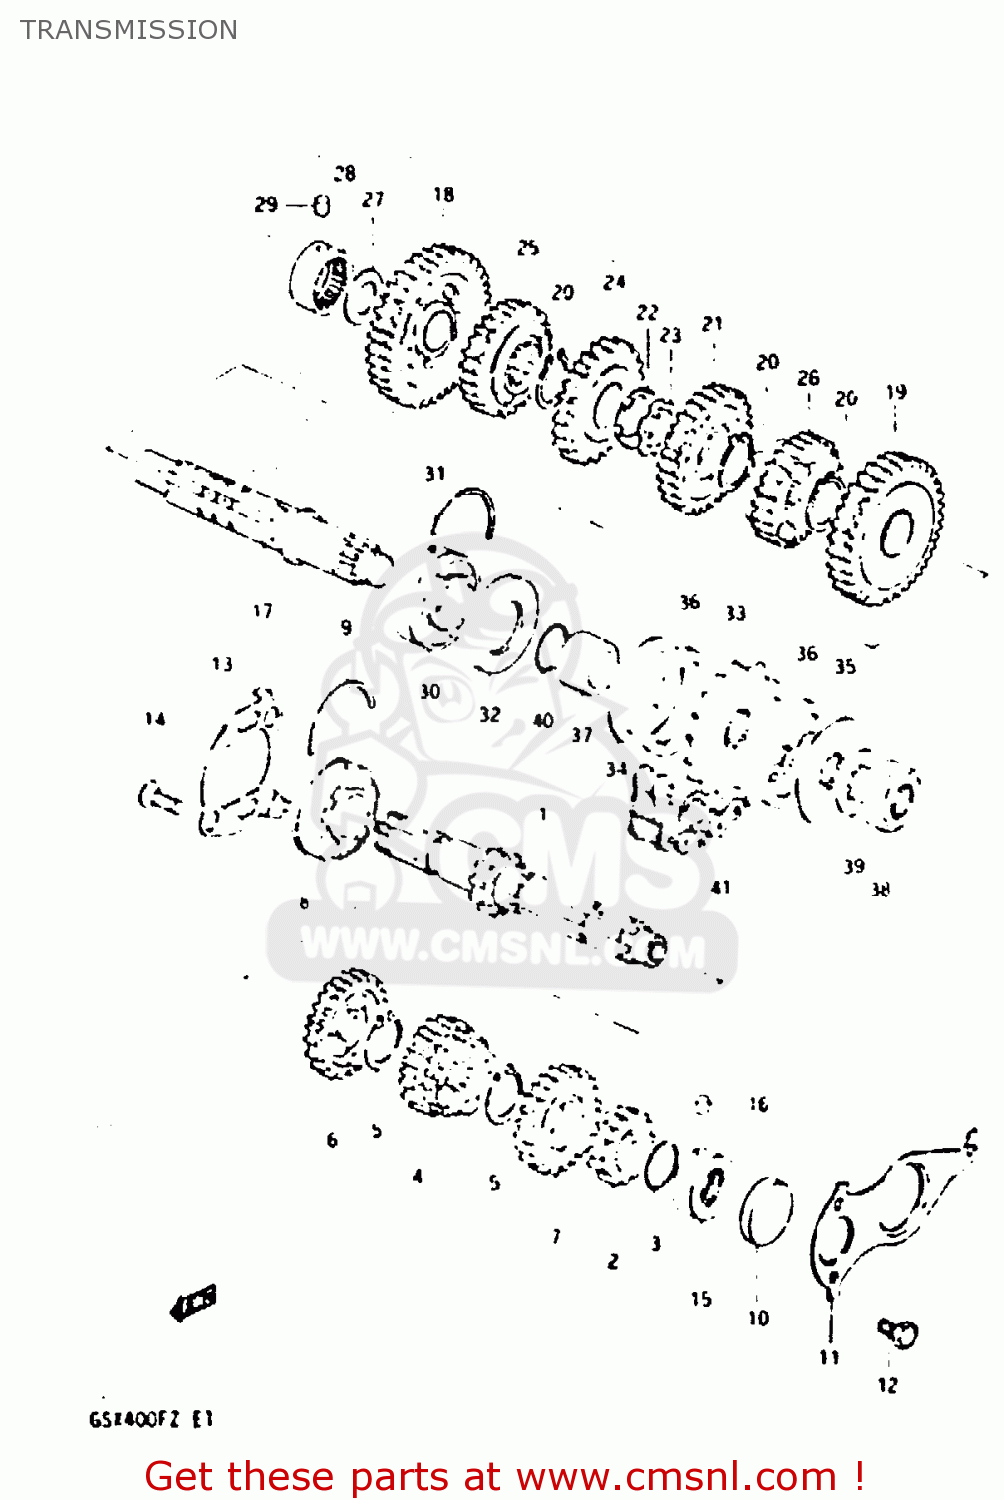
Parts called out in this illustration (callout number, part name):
1	COUNTERSHAFT ASSY
2	GEAR, 2ND DRIVE (NT:16)
3	CIRCLIP
4	GEAR, 3/4 DRIVE (NT:19/21)
5	CIRCLIP
6	GEAR, 5TH DRIVE (NT:23)
7	GEAR, 6TH DRIVE (NT:24)
8	BEARING, RH
9	C RING
10	PLUG
11	HOLDER
12	BOLT
13	HOLDER, BEARING
14	SCREW
15	BEARING, LH
16	PIN
17	DRIVESHAFT
18	GEAR, 1ST DRIVEN (NT:38)
19	GEAR, 2ND DRIVEN (NT:34)
20	CIRCLIP
21	GEAR, 3RD DRIVEN (NT:31)
22	WASHER
23	WASHER,LOCK
24	GEAR, 4TH DRIVEN (NT:28)
25	GEAR, 5TH DRIVEN (NT:27)
26	GEAR, 6TH DRIVEN (NT:26)
27	WASHER,THRUST
28	BEARING(20X34X20)
29	PIN
30	BEARING
31	C RING
32	OIL SEAL 30X56
33	SPROCKET,ENGINE
34	HOLDER, RH
35	HOLDER, LH
36	DAMPER,ENGINE SPROCKET
37	SPACER
38	NUT
39	WASHER,LOCK
40	O RING(D:1.7,ID:22)
41	CHAIN ASSEMBLY,DRIVE
